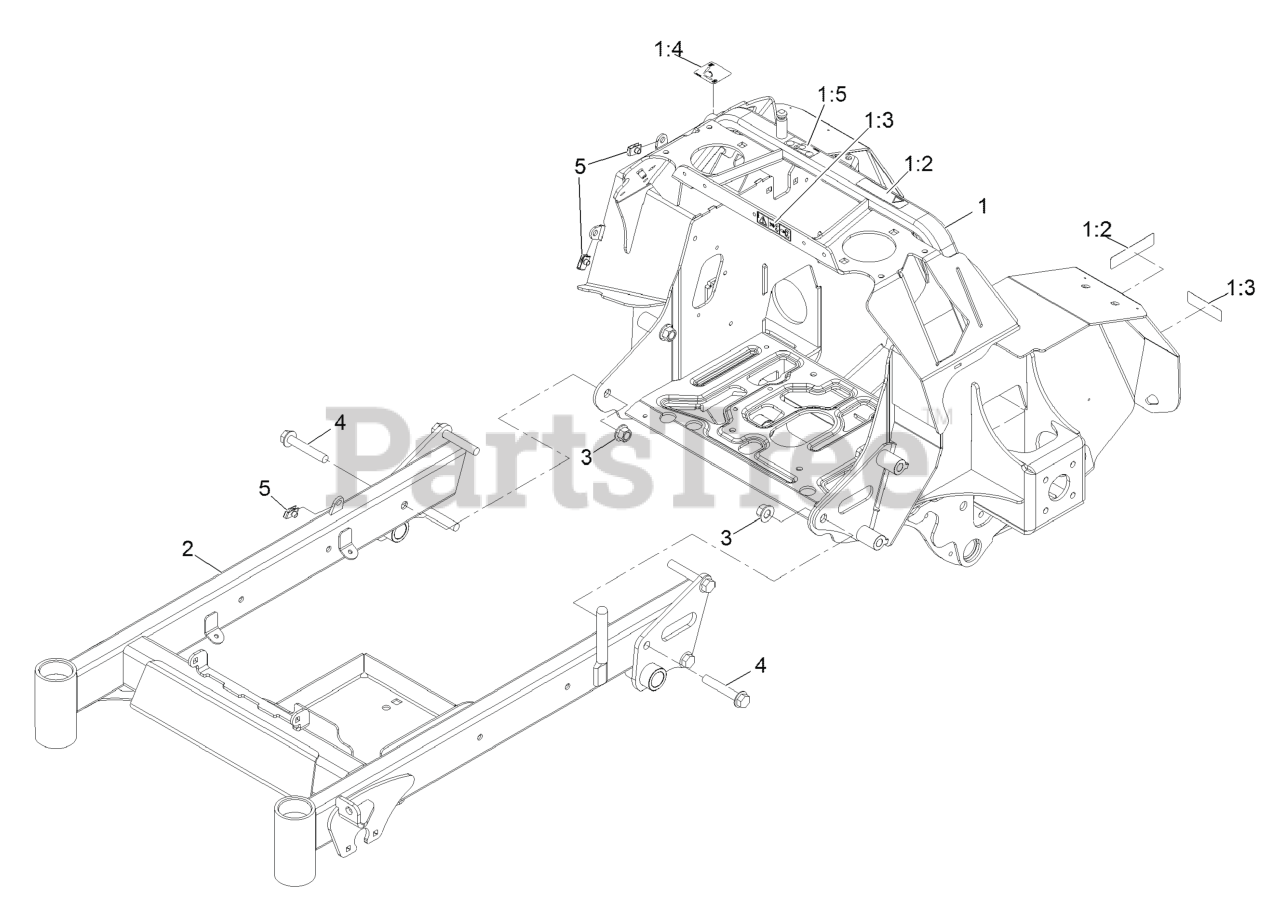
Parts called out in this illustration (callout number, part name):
1	ASM, REAR FRAME W/ DECALS
1:2	DECAL-WARNING
1:3	DECAL, COVER MISSING
1:4	DECAL-PARK BRAKE, CE
1:5	DECAL-BELT ROUTING HYD
2	WELD, FRONT FRAME, 36
3	Nut-Lock 1/2-13
4	SCREW-HF
21	SCREW, HSBH
